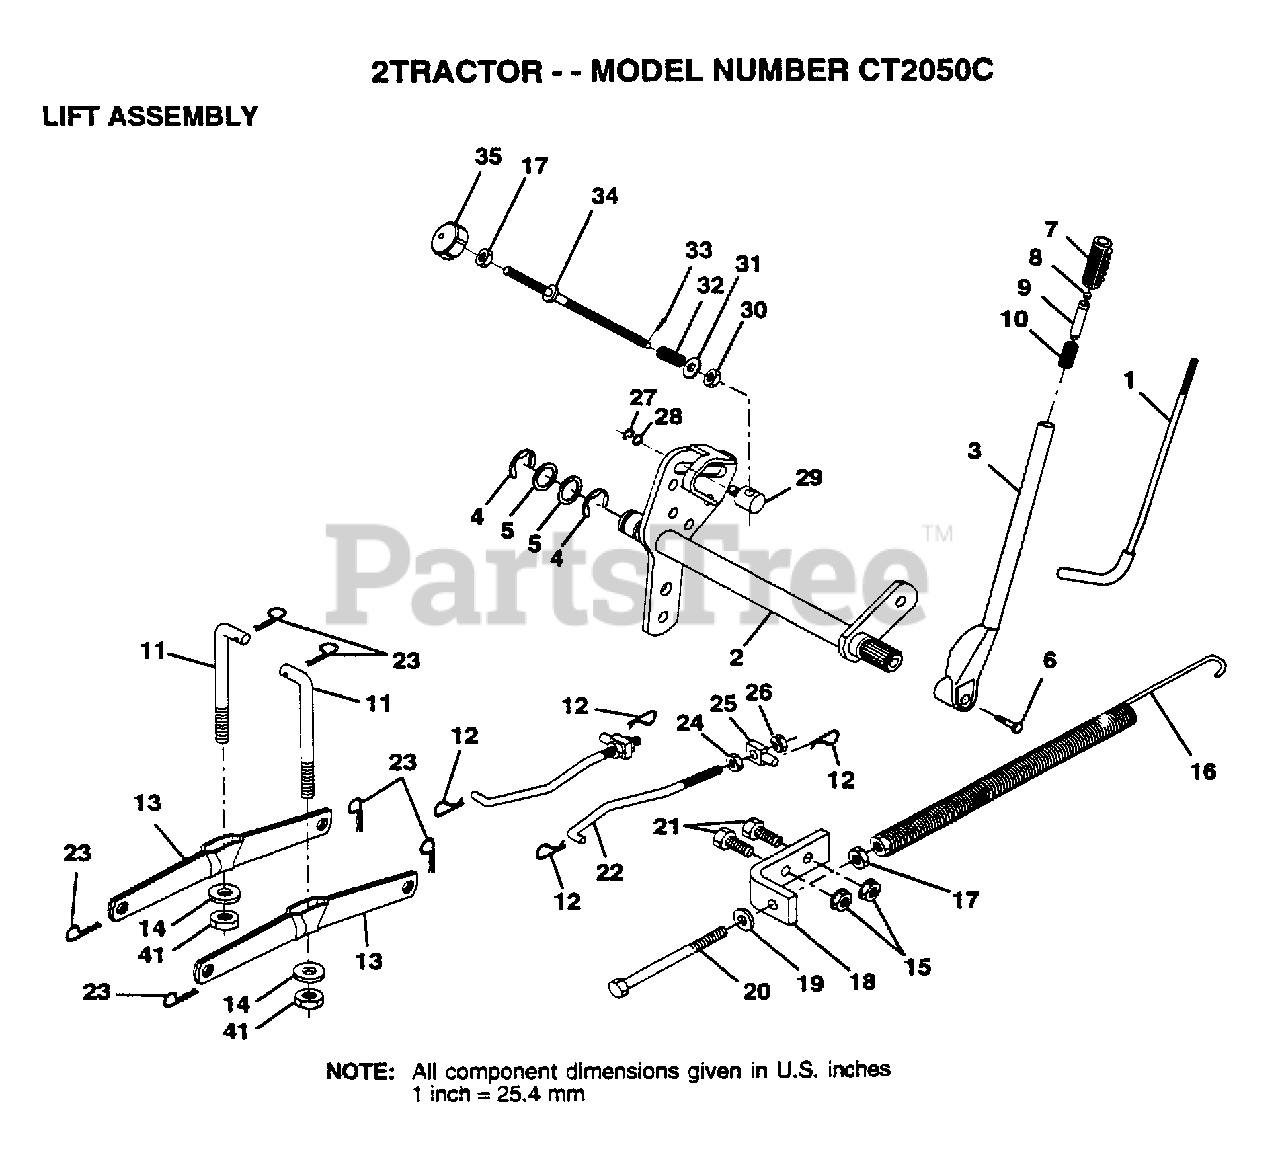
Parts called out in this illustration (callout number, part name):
1	LEVER ROD LT
2	SHAFT.LIFT.VGT.95
4	E-RING
5	WASHER
6	"BOLT,HEX"
7	GRIP
8	BUTTON PLUNGER YELLOW
10	SPRING T
11	LINK.LIFT.MWR.VGT
12	RETAINER.SPRING
13	ARM SUSP REAR
14	BEARING PVT LH
17	NUT
18	BRACKET SPRING AS
19	WASHER
20	BOLT-ADJ SPRING T
21	BOLT
22	LINK.FRONT
24	NUT
25	TRUNION
26	NUT.LK.W/WSH.1/2.
27	KLIP RING
28	WASHER
29	TRUNION LT
30	NUT T
31	WASHER
32	SPRING.COMP.INF.H
34	ROD.ADJ.LIFT
35	KNOB INF 3/8-16
41	NUT.CROWNLOCK.3/8
